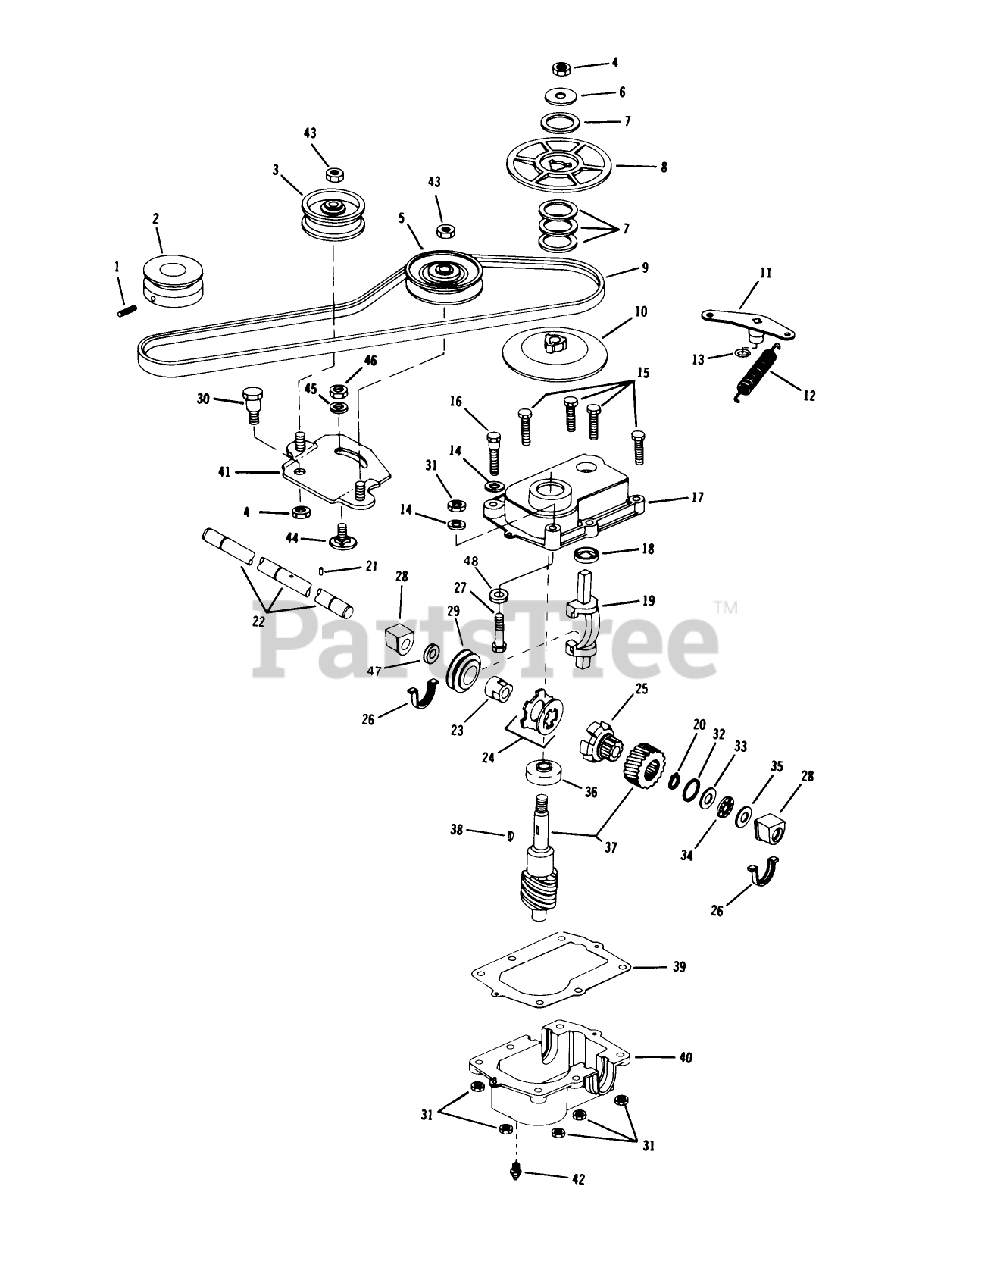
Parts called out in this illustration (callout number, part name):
1	SET SCREW F
2	PULLEY F
3	PULLEY NEWHAM IND *B
4	LOCKNUT
5	IDLER NEW HAM IND
6	WASHER
8	PULLEY UPPER PL
9	V-BELT
10	PULLEY LOWER PL
12	SPRING
13	O-RING
18	GUIDE ELCO
20	RET RING
21	PIN DRIVE LOCK
25	DRIVER BROCKWAY
28	BEARING & SEAL AY (12)
31	LOCKNUT E
33	WASHER-THRUST
35	THRUST WASHER
36	BEARING-BALL
38	KEY GALGER
39	GASKET HOOSIER
42	FITTING LINCOLN
43	NUT-JAM, LOCKING
45	WASHER M
46	NUT-LOCK F
47	WASHER
